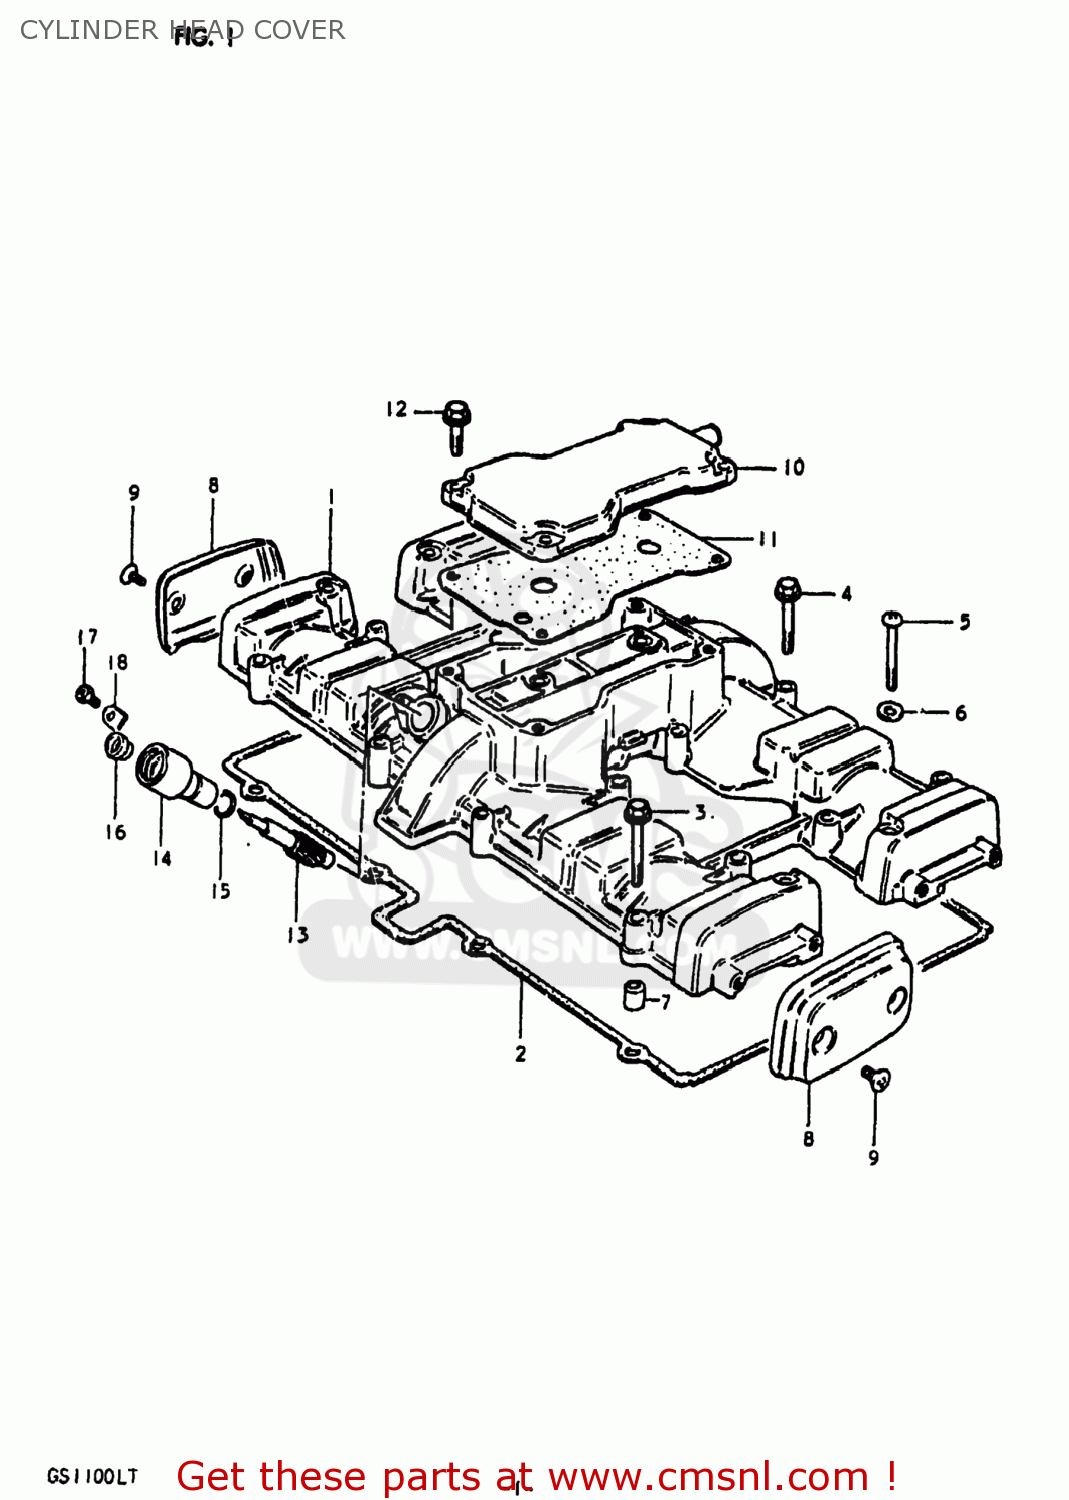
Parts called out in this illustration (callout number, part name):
1	COVER,CYLINDER HEAD
2	GASKET,CYLINDER HEAD COVER (MCA)
3	BOLT
4	BOLT 6X35
5	SCREW 6X40
6	GASKET (NAS)
7	PIN(6.2X8X11)
8	CAP,CYLINDER HEAD COVER
9	SCREW 5X12
10	COVER,BREATHER
11	GASKET (MCA)
12	BOLT,REAR
13	GEAR,TACHOMETER DRIVEN
14	SLEEVE,TACHOMETER DRIVE
15	SEAL,TACHOMETER DRIVEN
16	SEAL,OIL(5X12X8)
17	SCREW(5X12)
18	PLATE,TACH DRIVE GEAR SLEEVE
